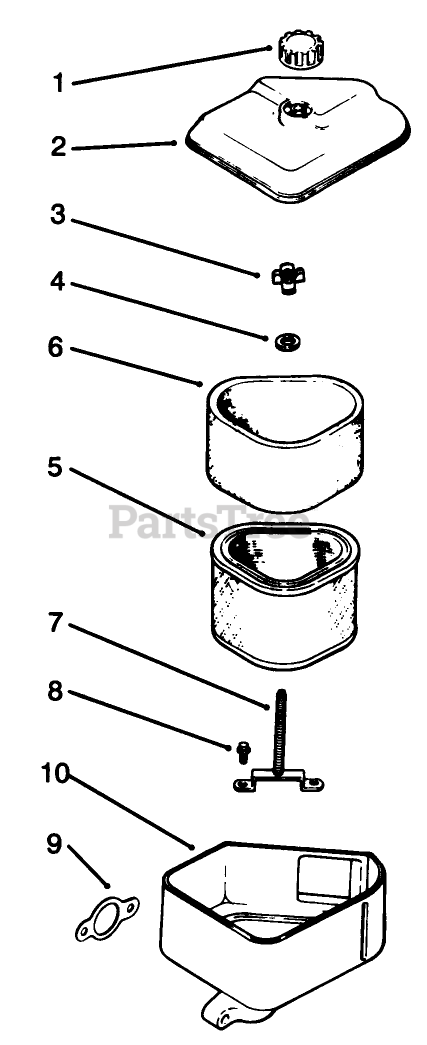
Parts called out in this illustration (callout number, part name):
1	Knob-Air Cleaner Cover (Only On: 72042, 72043, 72062, 72063)
2	Cover-Air Cleaner (Only On: 72042,72043,72062,72063)
3	Nut-Wing
4	Washer
5	Element-Air Cleaner (Only On: 72042, 72043, 72062, 72063)
6	Precleaner-Element (Only On: 72042,72043,72062,72063)
7	Stud-Mounting Plate (Only On: 72042, 72063, 72062, 72043)
8	Screw-Mounting Plate (Only On: 72042, 72043, 72062, 72063)
9	Gasket-Air Cleaner (Only On: 72042, 72043, 72062, 72063)
10	Base-Air Cleaner (Only On: 72042, 72043, 72062, 72063)
